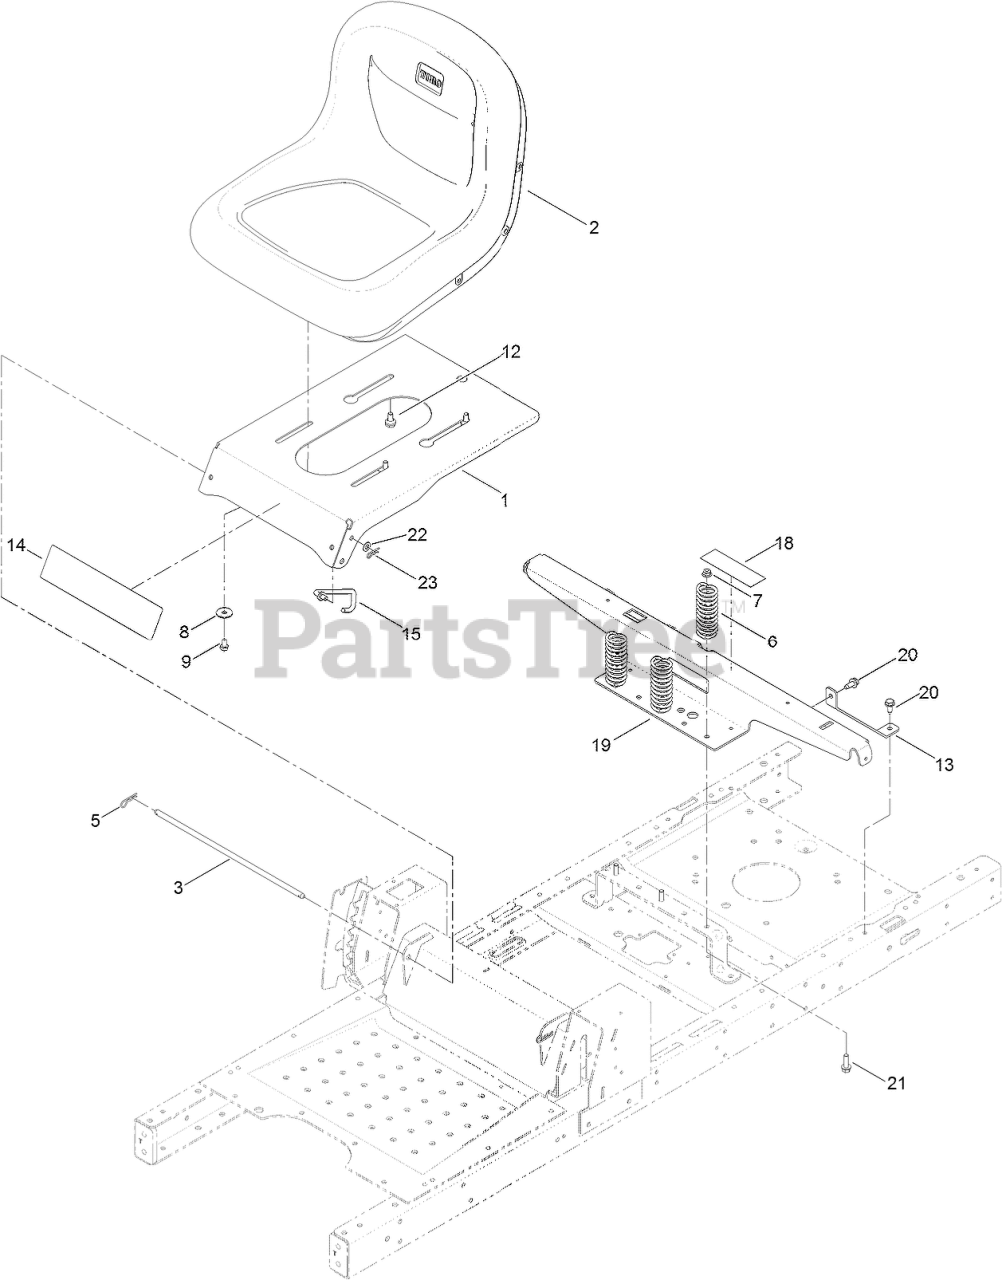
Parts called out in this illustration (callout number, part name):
1	PAN-SEAT
2	SEAT-15 INCH
3	ROD-PIVOT, NARROW
5	PIN-COTTER
6	SPRING-COMPRESSION
7	NUT-HF, NI
8	WASHER-PIVOT
9	SCREW-HH
12	BOLT-SHOULDER
13	SUPPORT-TANK, REAR
14	DECAL-TIMECUTTER
15	STOP-SEAT
18	DECAL-SERVICE, CE
19	SUPPORT-POD
20	SCREW-HWHTF
21	SCREW-HHF
22	WASHER-PLAIN
23	PIN-COTTER
